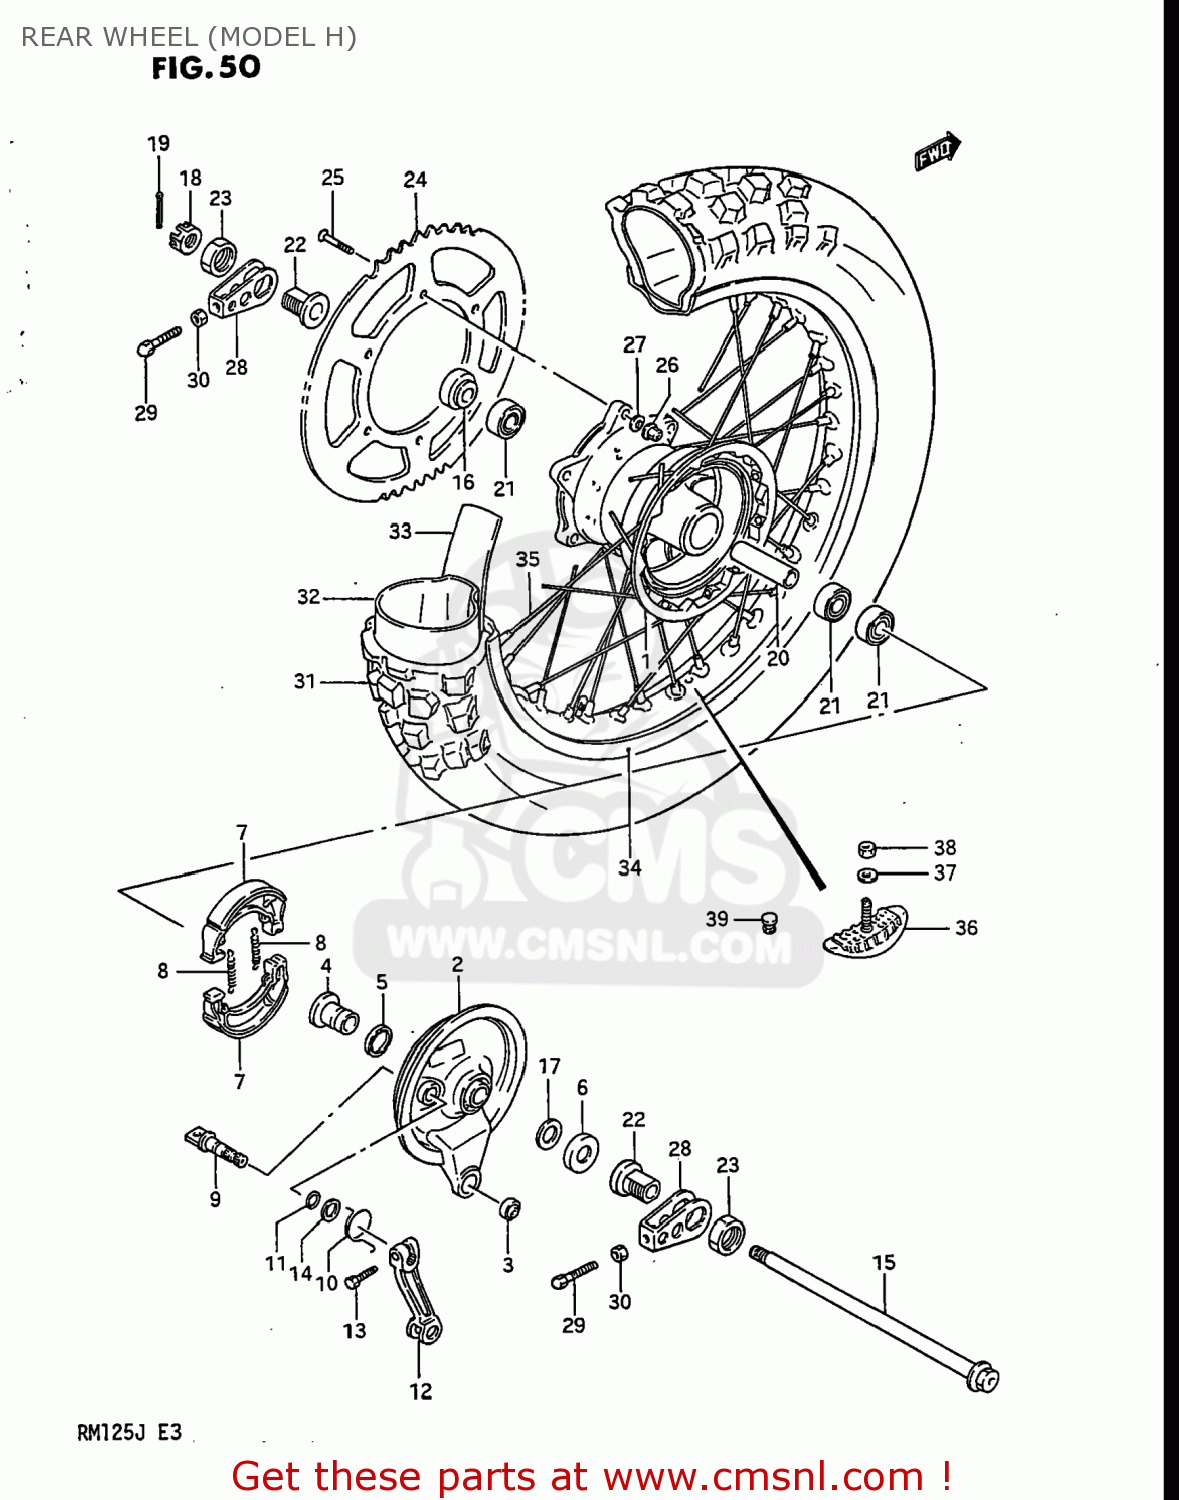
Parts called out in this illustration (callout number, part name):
1	HUB,REAR WHEEL
2	PANEL SET,REAR
3	BEARING
4	SPACER,RR BR AHR PNL
5	SEAL,OIL(20X27X5)
6	CVR,RR BRAKE AHR PNL DUST SEAL
7	SHOE,BRAKE (MCA)
8	SPRING(L:34)
9	CAM,FR BRAKE
10	SPRING
11	O RING(D:2.5,ID:11.4)
12	LEVER,REAR BRAKE CAM
13	BOLT
14	WASHER(12.5X20X1)
15	AXLE,REAR
16	SPACER,RR AXLE,L
17	WASHER,THRUST
18	NUT
19	COTTER PIN
20	SPACER,REAR HUB BEARING
21	BEARING(15X35X11)
22	SPACER,CHAIN ADJUSTER
23	NUT
24	SPROCKET,RR(NT:51 AL)
25	SCREW(8X33.5)
26	NUT
27	WASHER
28	ADJUSTER,CHAIN
29	BOLT(8X43)
30	NUT
31	TIRE
32	TUBE ASSEMBLY,WHEEL,INNER
33	PROTECTOR
34	RIM,REAR WHEEL (1.85X18 A)
35	SPOKE SET,RR WHEEL
36	STOPPER,BEAD
37	WASHER
38	NUT 8MM
39	CAP(OD:12)
